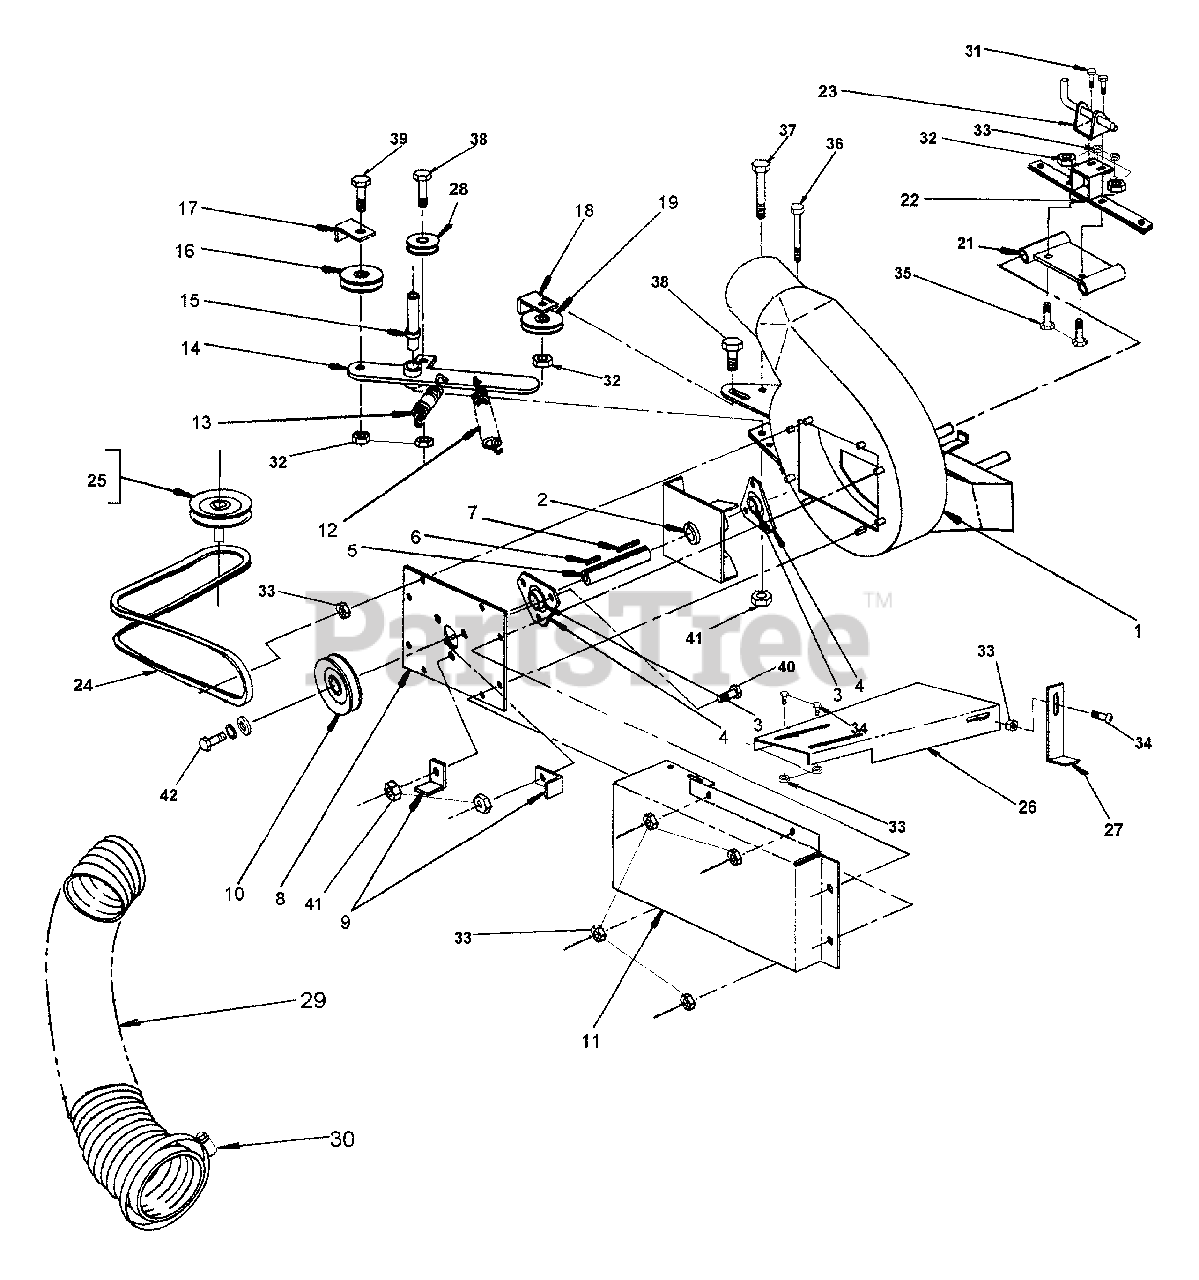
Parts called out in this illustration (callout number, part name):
1	Blower Housing
3	Bearing
4	Flange, Bearing (set of 2)
5	Fan Shaft
6	1/4" x 3/4" key
7	1/4" x 1 1/4" key
8	Back Canister Cover
9	Fan Pulley Belt Bracket
10	Fan Drive Pulley
11	Blower Belt Cover
12	7/8" x 6" Spring
13	13/16" x 3 1/8" Spring
14	Idler Arm
15	Idler Arm Pivot
16	Flat Idler Pulley
17	Lower Pulley Bracket
18	Upper Pulley Bracket
19	V-Idler Pulley
21	Lower Mounting Bracket
22	Upper Mounting Bracket
23	Sprig Latch
24	87" A-sec. Belt
25	Drive Pulley
26	Belt Guard
27	Belt Guard
28	2.5" V-Idler Pulley
29	43" Urethane Hose
30	Hose Clamp
